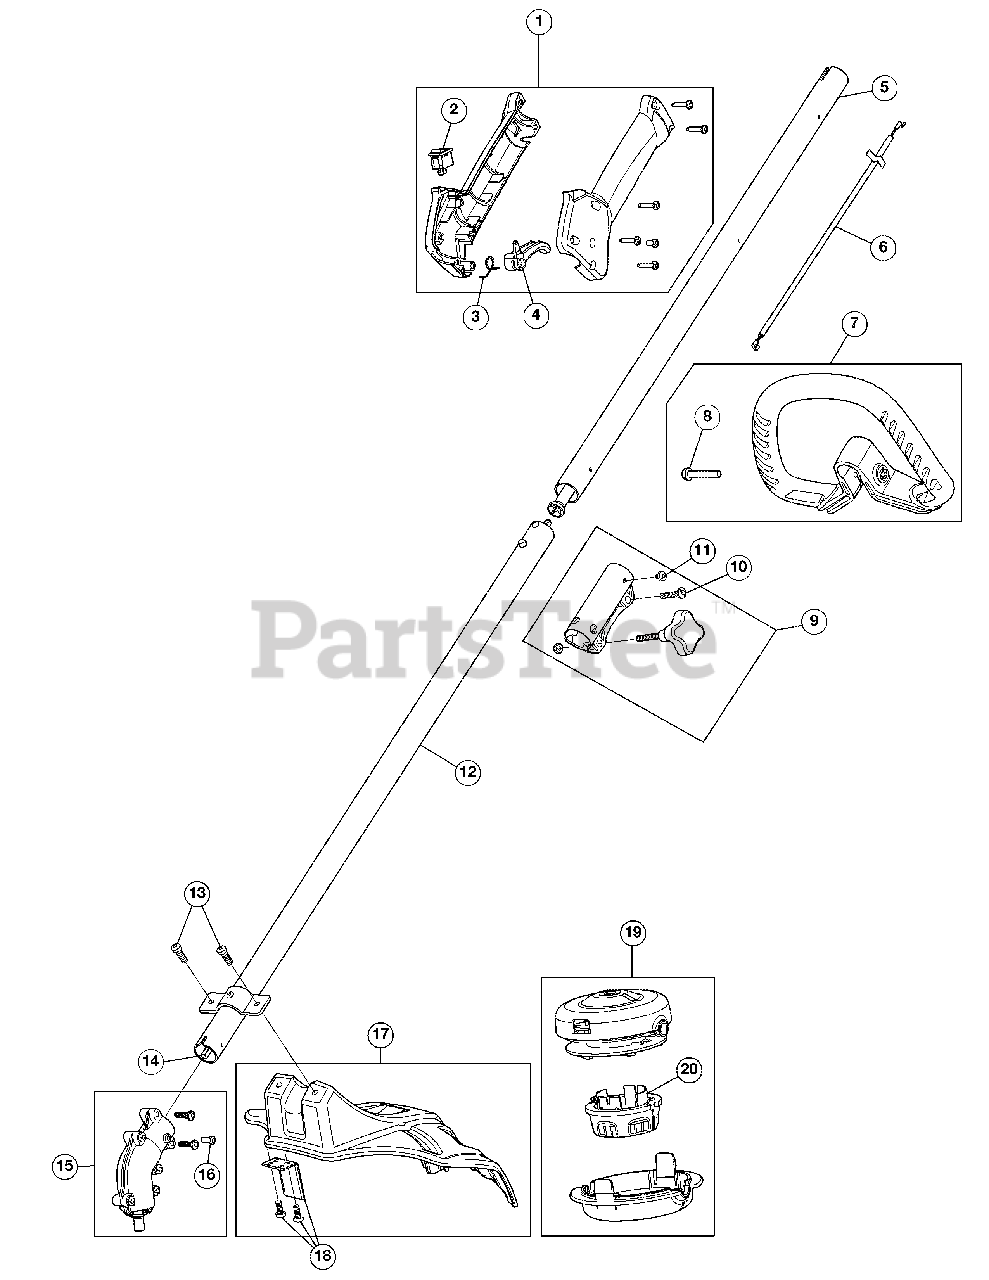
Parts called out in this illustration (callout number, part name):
1	Throttle Housing Assembly (Incl. 2 - 4)
2	Switch Assembly
3	Throttle Trigger Spring
4	Throttle Trigger
5	Upper Drive Shaft Assembly
6	Throttle Cable Assembly
7	D-Handle Assembly (Incl. 8)
9	Split Boom Coupler (Incl. 10 -11)
10	Coupler Bolt
11	Coupler Anti-Rotation Screw
12	Lower Drive Shaft Housing
13	Shield Mount Screw Assembly
14	Lower Flexible Drive Shaft
15	Gearbox Assembly (Incl. 16)
17	Shield Assembly (Incl. 18)
18	Blade Assembly
19	Cutting Head Assembly (Incl. 20)
